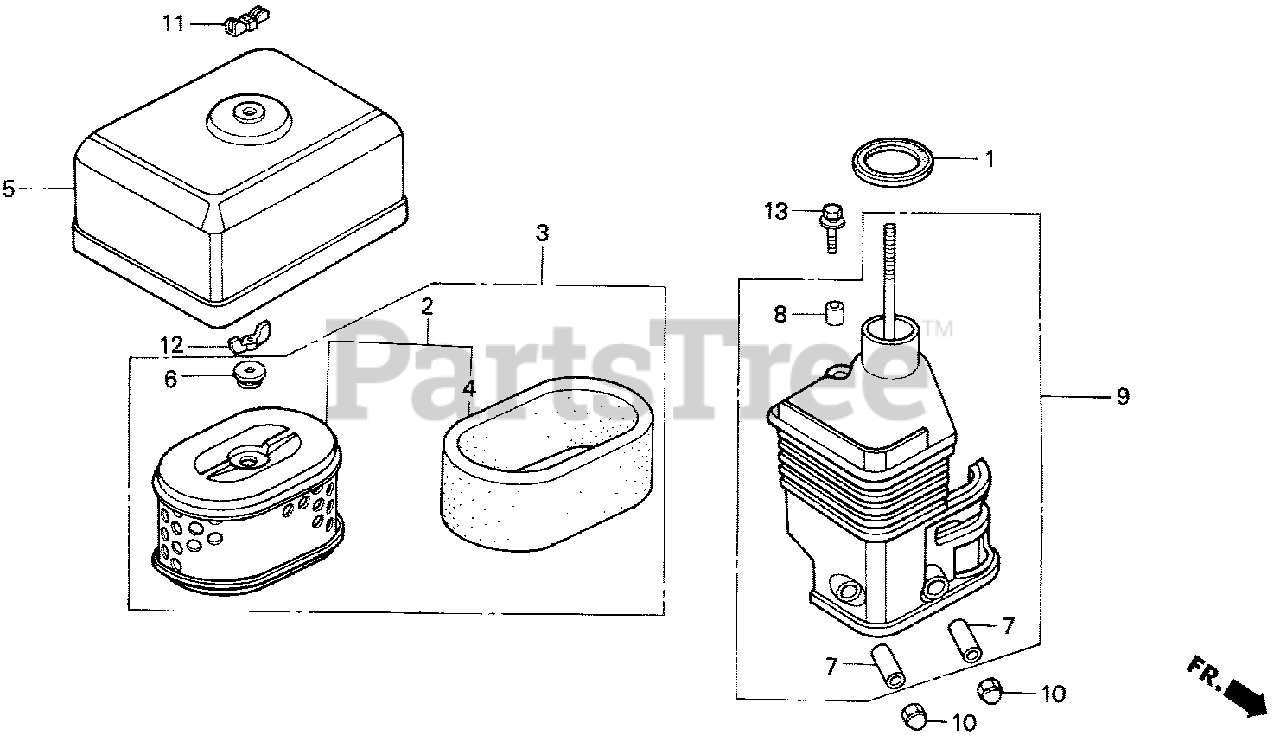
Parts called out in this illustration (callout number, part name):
1	GASKET, ELBOW
2	ELEMENT, AIR CLEANER (DUAL)
3	ELEMENT, AIR CLEANER (DUAL)
4	FILTER (OUTER)
5	COVER, AIR CLEANER (DUAL)
6	GROMMET, AIR CLEANER
7	COLLAR, AIR CLEANER
8	COLLAR B, AIR CLEANER
9	ELBOW, AIR CLEANER
10	NUT, CAP (6MM)
11	WINGNUT, AIR CLEANER COVER
12	WINGNUT, TOOL BOX SETTING
13	BOLT-WASHER (6X20)
